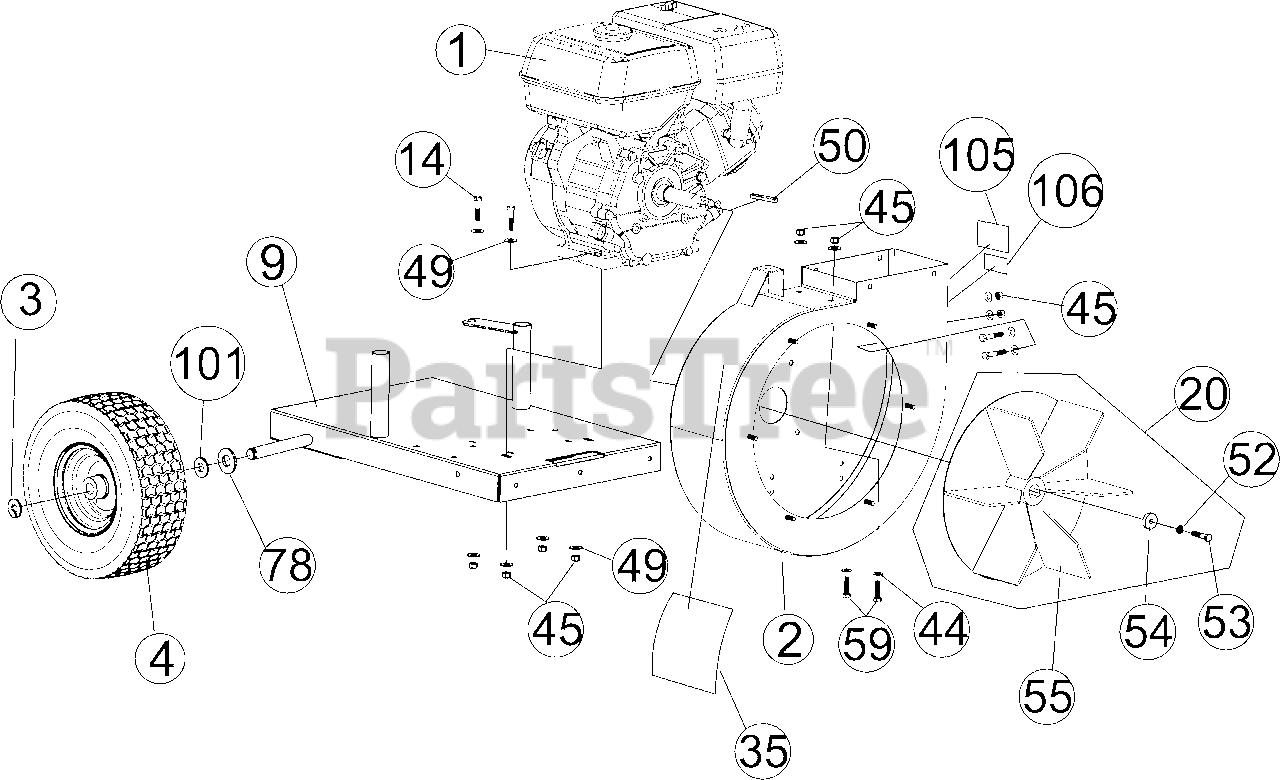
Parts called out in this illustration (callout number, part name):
1	ENGINE HONDA 5.5 OHV GX160
2	HOUSING WA W/LABELS
3	SNAP RING 3/4
4	WHEEL 13" X 5" PNEU
9	ENGINE BASE WA
14	SCREWCAP 5/16"-18 X 1 1/2" HCS ZP
20	IMPELLER ASSY
35	LABEL WARNING QV
44	WASHER 5/16" SAE
45	NUT LOCK 5/16"-18 HEX ZP
49	WASHER 5/16" FLAT
50	KEY 3/16" SQ X 2 1/4"
52	WASHER LOCK 5/16" SPLIT
53	SCREWCAP 5/16"-24 X 2 1/4" GR.8 W/PATCH
54	WASHER 1.125 OD X 0.344 ID X0.25
55	IMPELLER 5HP WA (torque 17-22 ft.lbs [23-30 N.m])
59	SCREWCAP 5/16"-18 X 3/4" GR 5 HCS ZP
78	WASHER 3/4" SAE
101	WASHER .765 ID X 1.25 OD X .06
105	LABEL MADE IN USA
106	LABEL PATENT PENDING
107	BRACKET BRAKE QV
108	BOLT SHOULDER 3/8" X 1/2"
